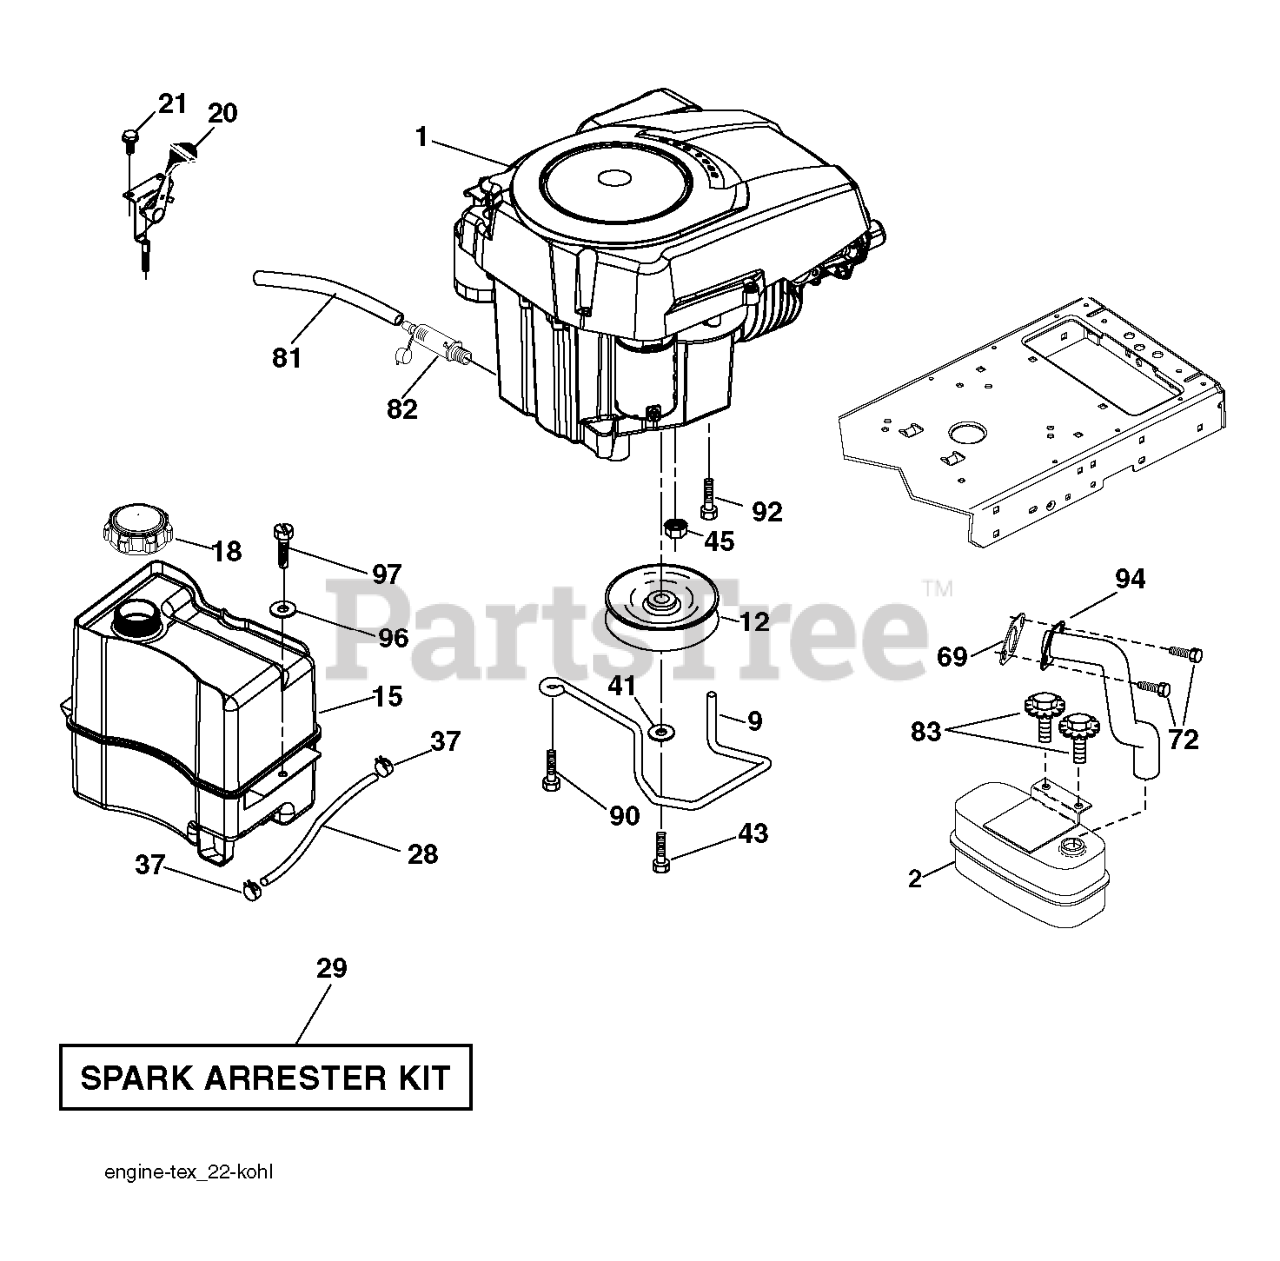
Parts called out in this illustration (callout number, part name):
2	MUFFLER.SINGLE.CYL.KOHL/B&S
9	KEEPER.BELT.ENGINE.3.25 (3 2)
12	PULLEY ENGINE
15	RP TANK FUEL FRT 1.5 GAL
18	FUEL CAP
20	CONTROL.TH/CK.C.
21	SCREW.#10 X 0.750.BOS
28	LINE.FUEL.20
29	KIT.SPARK ARRESTOR 794945 B&S
37	HOSE CLAMP
41	LOCKWASHER
43	BOLT HEX 7/16-20X4-1/4"
45	NUT
69	GASKET.EXHAUST.KOHLER
72	SCREW.SOCKET HD.5/16-1
81	TUBE, DRAIN OIL ASM.
82	PLUG DRAIN OIL EASY
83	BOLT.5/16-18UNCX3/4 W/SEMS.BLK
90	SCREW 3/8-16X1
92	SCREW 3/8-16X1
94	RP.TUBE.EXHAUST.KOHL.COURAGE
97	SCREW HEXWSHR 1/4-20X3/4
